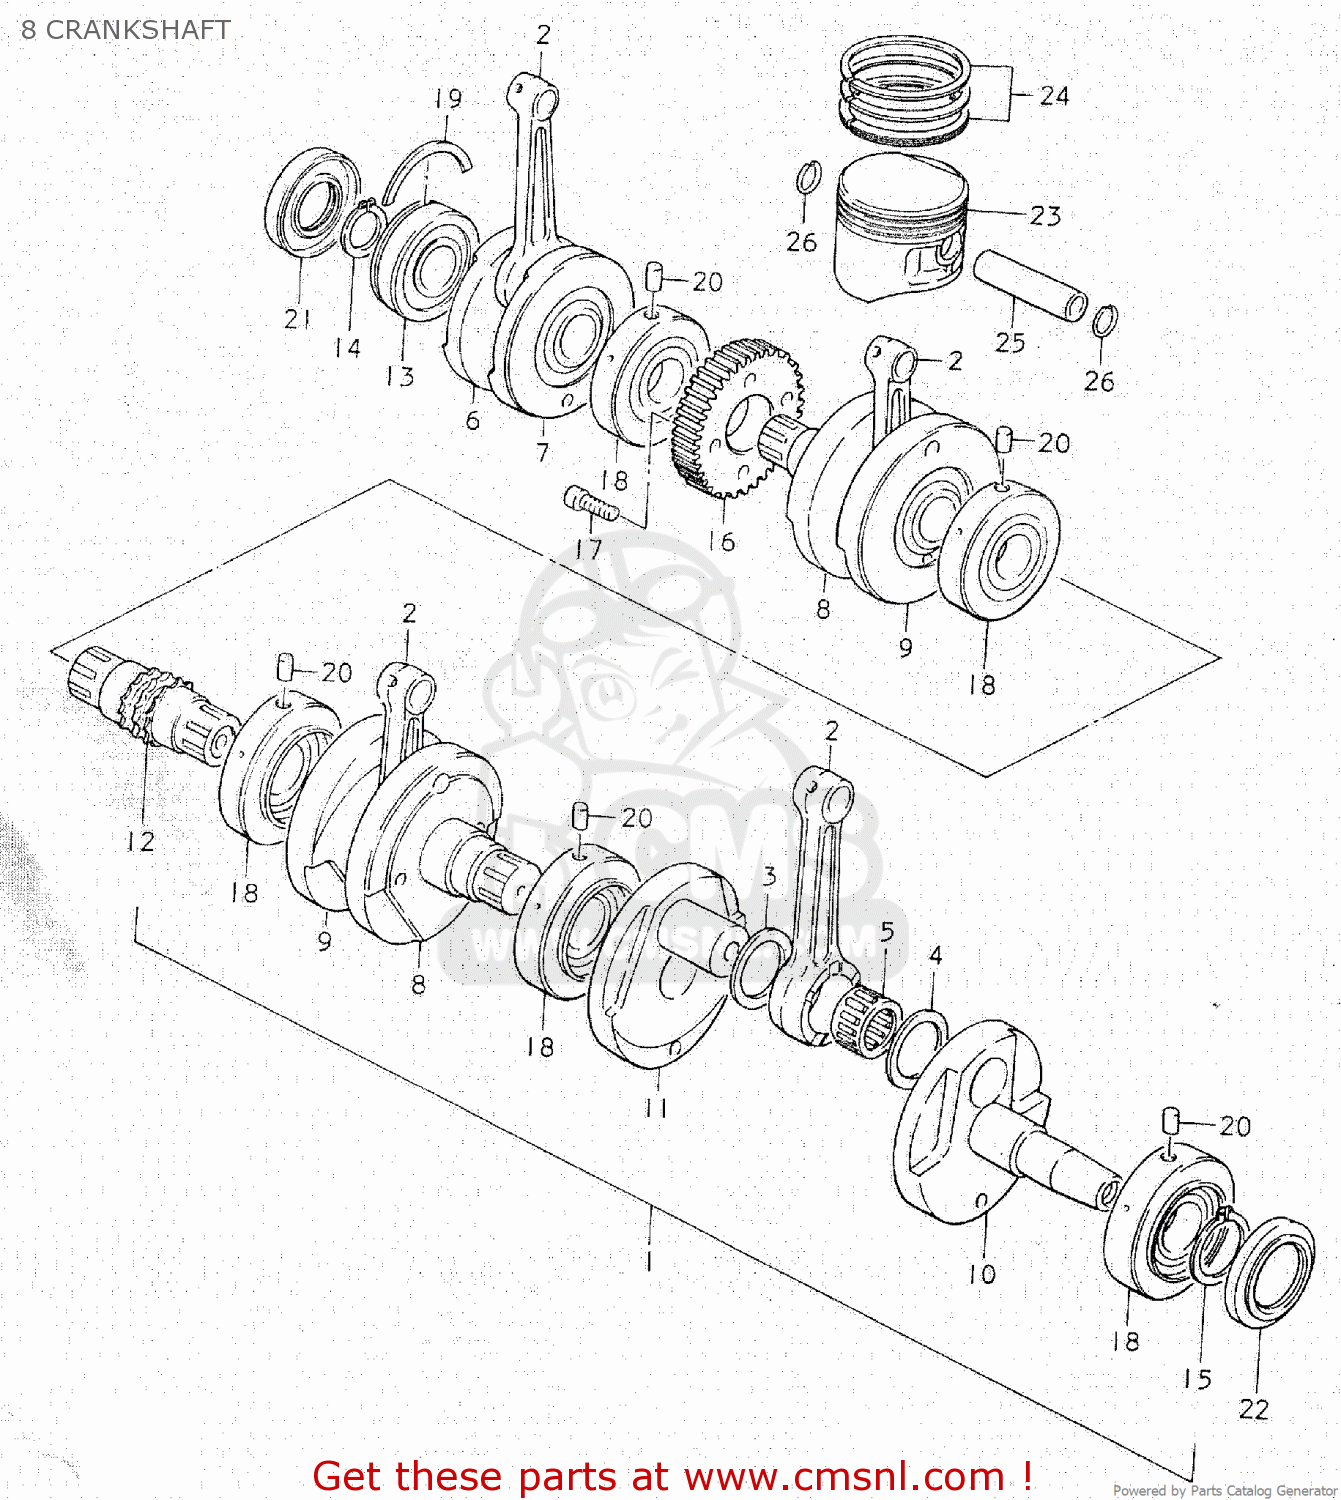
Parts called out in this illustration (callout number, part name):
1	CRANKSHAFT ASSEMBLY
2	CONNECTING ROD
3	WASHER (28X48X2)
4	WASHER(28X48X1)
5	BEARING(28X38X19.8)
6	CRANKSHAFT
7	WEB,CRANK
8	CRANKSHAFT
9	WEB,CRANK,MIDDLE
10	CRANKSHAFT,LEFT
11	WEB,CRANK
12	SHAFT,TIMING CHAIN DRIVE
13	BEARING(30X72X19)
14	CIRCLIP,30MM
15	CIRCLIP.32MM
16	GEAR,PRIMARY DRIVE
17	BOLT
18	BEARING
19	C RING
20	PIN
21	SEAL,OIL(30X72X11)
22	OIL SEAL
23	PISTON
24	PISTON RING SET
25	PIN,PISTON
26	CIRCLIP
